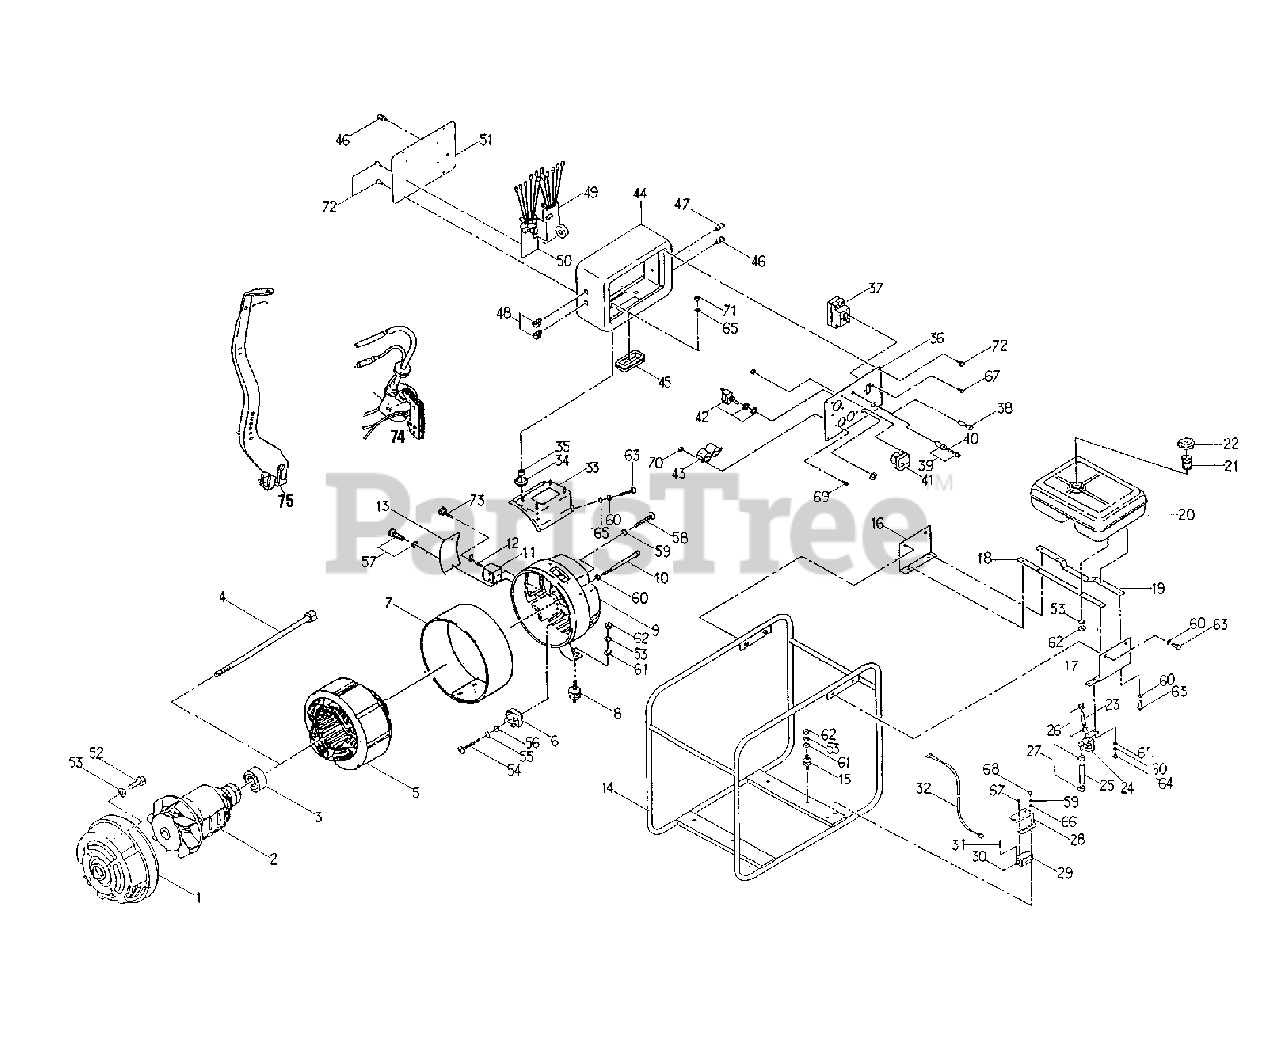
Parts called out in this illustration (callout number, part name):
1	BRACKET - FRONT
2	ROTOR ASSY
3	BEARING, BALL
4	THRU BOLT
5	STATOR ASSY
6	BLOCK, DIODE
7	STATOR COVER
8	RUBBER MOUNT
9	BRACKET - REAR
10	BOLT, BRACKET
11	HOLDER, BRUSH
12	BRUSH UNIT
13	COVER, BRUSH
14	TUBE, FRAME
15	RUBBER MOUNT
16	BRACKET, TANK
17	BRACKET, TANK
18	BRACKET, FUEL TANK
19	BRACKET, FUEL TANK
20	FUEL TANK ASSY
21	FILTER, FUEL
22	CAP ASSY
23	HOSE - RUBBER
24	STRAINER, FUEL
25	HOSE - RUBBER
26	CLAMP, HOSE
27	CLAMP, HOSE
28	BRACKET, SOLENOID
29	SOLENOID
30	SPRING
31	PIN, SPLIT
32	WIRE ASSY
33	BOX BASE
35	SPACER
37	BREAKER - 20A
38	NEON LAMP - 110V
39	HOLDER, FUSE
40	FUSE
41	METER - 150V
43	OUTLET - 125V 15A X 2
44	CONTROL BOX ASSY
46	OUTPUT TERMINAL - BLACK
47	OUTPUT TERMINAL - RED
48	CORD BUSHING
49	AUTOMATIC IDLE RETURN
50	AVR UNIT
51	PANEL B
52	BOLT
53	LOCKWASHER - 8
54	SCREW - 4X18
55	LOCKWASHER - 4
56	WASHER - 4
57	SCREW - 5X10 -- TAPPING
58	SCREW - 5X16
59	LOCKWASHER - 5
60	LOCKWASHER - 6
61	WASHER - 8
62	NUT - 8
63	BOLT - 6X15
64	BOLT - 6X12
65	WASHER - 6
66	WASHER - 5
67	SCREW - 3X8 -- TAPPING
68	BOLT - 5X12
69	SCREW - 4X10 -- TAPPING
70	NUT - 4
71	NUT - 8
72	SCREW - 4X6 -- TAPPING
73	SCREW - 3X4.5 -- TAPPING - BRASS
74	IGNITION UNIT
75	LEVER, GOVERNOR
